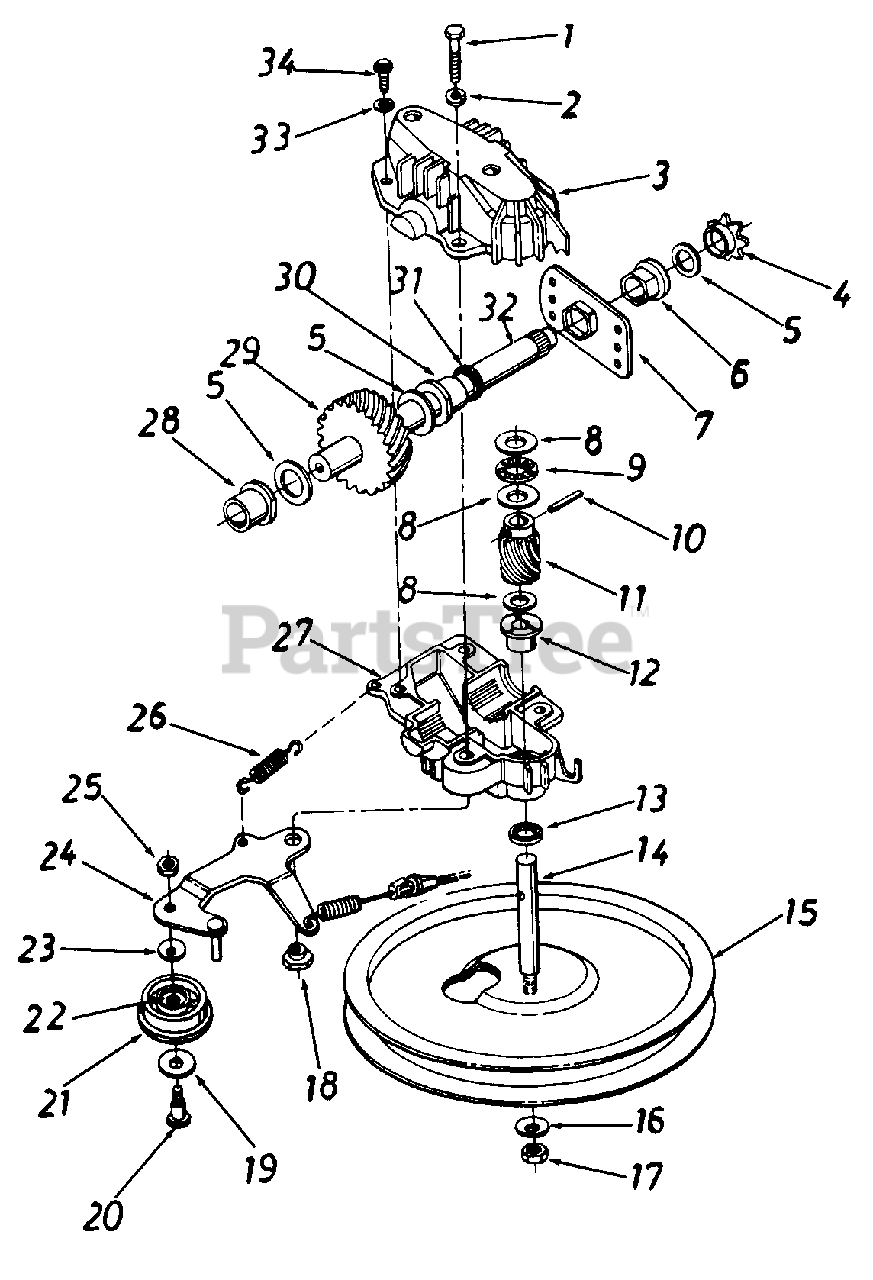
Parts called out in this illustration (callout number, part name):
1	Hex Boit 1/4-20 x 1.25" Lg.
2	L-Wash. 1/4" I.D.
3	Upper Transmission Hsg. Half
4	#48 Sprocket 7 Tooth x 1/2 Pitch
5	Fl-Wash. 5/8" I.D. x .030
6	Hex Flange Brg. .631" I.D.
7	Hex Bearing Cup
8	Thrust Wash. .382" I.D. x .70" O.D.
9	Thrust Bearing .375" I.D. x .812" O.D.
10	Spring Pin Spir. 1/8" x .62" Heavy
11	11 Tooth Helical Gear
12	Flange Bearing
13	Oil Seal
14	Pulley-Transmission Shaft .375 O.D.
15	Fl-Pulley 5.06" O.D.
16	Bell-Wash. .265" I.D. x .75" O.D.
17	Hex Lock Nut 1/2-20 Thd.
18	Shld. Spacer .375" Dia. x .170
19	Fl-Wash. .390" I.D. x 1.0" O.D.
20	Shld. Bolt .375" Dia. x .400" Lg.
21	Fl-Idler Plastic 1.50" Dia. x .48
22	Needle Brg. .375" x .31
23	Bell-Wash. .265" I.D. x .75" O.D.
24	Idler Brk't. Ass'y.
25	Hex Patch L-Nut 1/4-20 Thd.
26	Extension Spring 1.12" Lg.
27	Lower Transmission Hsg. Half
28	Flange Bearing .566 Dia.
29	33 Tooth Helical Gear
30	Flange Bearing .629 Dia.
31	Oil Seal .625 Dia.
32	Gear Sprocket Shaft
33	L-Wash. #10
34	Hex B-Tap Scr. #10 x .62"
